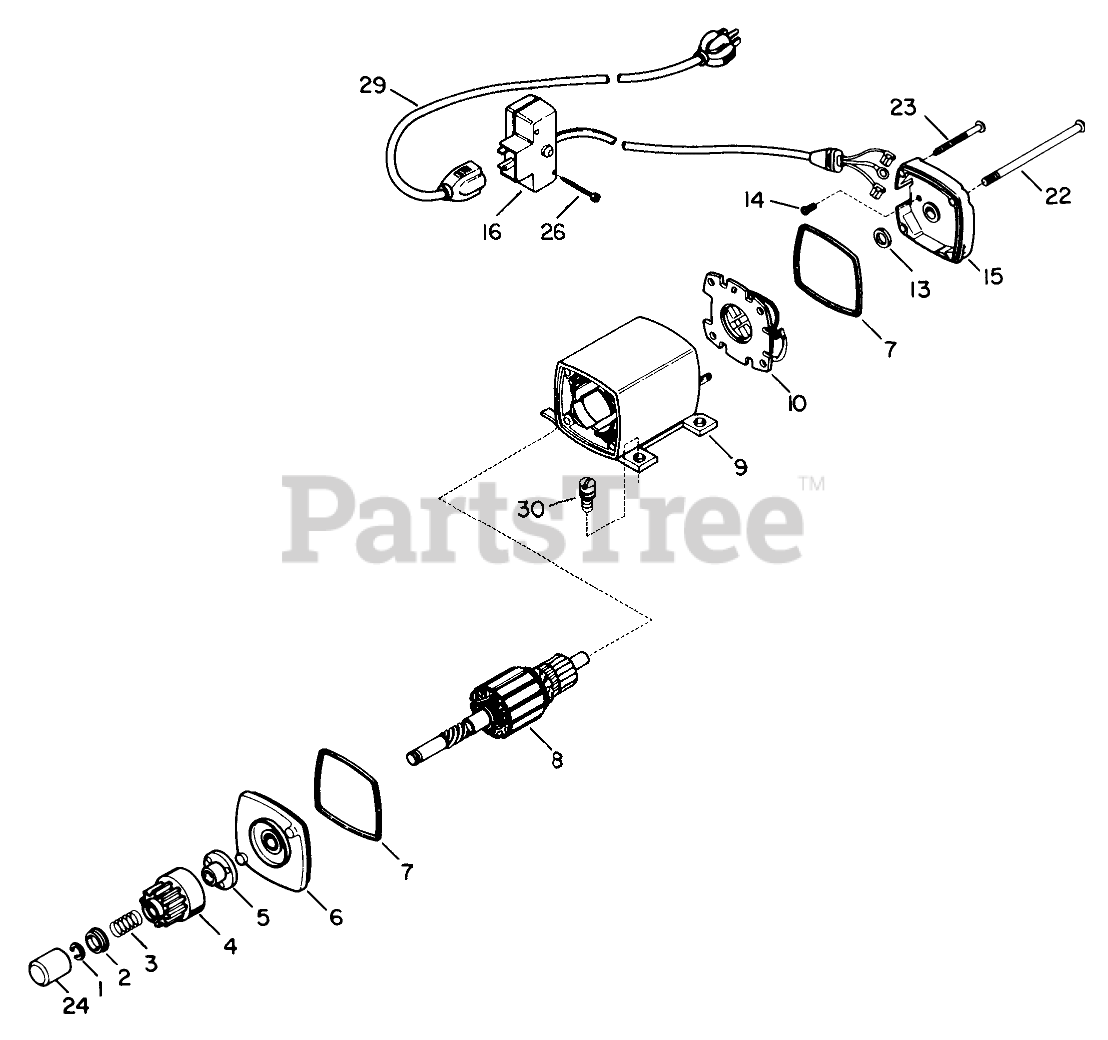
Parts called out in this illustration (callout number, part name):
1	Ring-Retainer
2	Retainer-Spring
3	Spring-Anti Drift
5	Nut-Engaging
6	Drive End Cap ASM (Incl. Ref. #7)
8	Armature
9	Housing ASM
10	Card ASM
13	Washer-Thrust
14	Screw-Ground
15	Commutator End Cap ASM (Incl. Ref. #7)
16	Switch Box ASM
22	Bolt-Case
23	Screw-Ground
24	Cover-Dust
29	Cord-Extension
